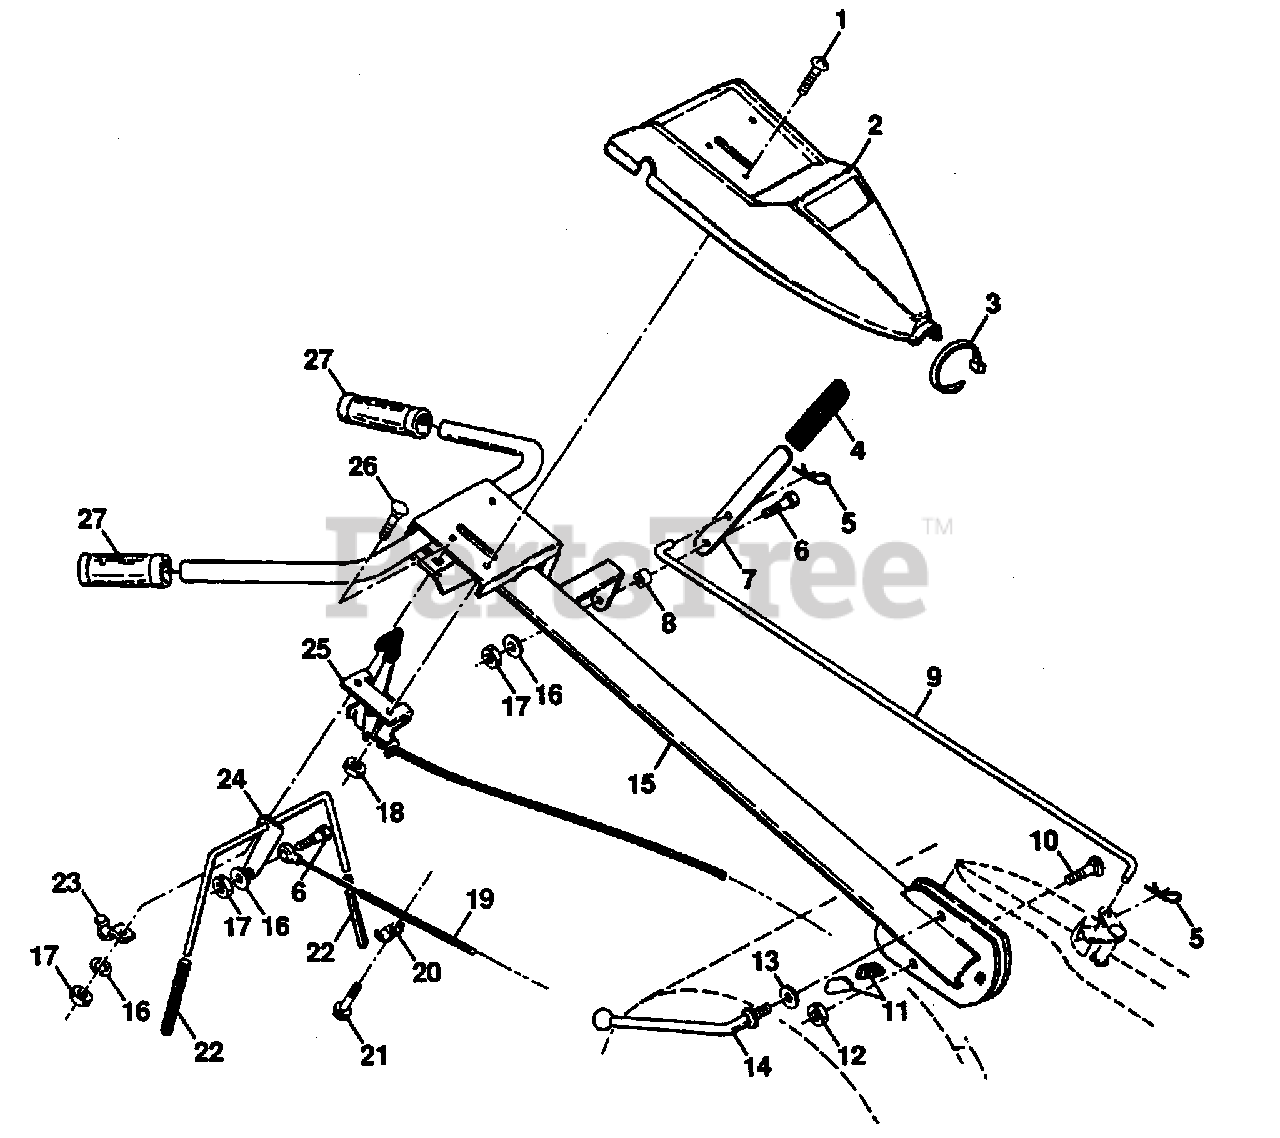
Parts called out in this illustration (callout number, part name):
1	Screw, Truss Hd. #10-24 UNC x 1/2 (AYP part number)
2	Panel, Control (AYP part number)
3	Tie, Cable (AYP part number)
4	Grip, Handle (AYP part number)
5	Clip, Hairpin (AYP part number)
6	Bolt, Shoulder (AYP part number)
7	Handle, Shift (AYP part number)
8	Grommet, Rubber (AYP part number)
9	Rod, Shift (AYP part number)
10	Bolt, Carriage 3/8-16 x 1 Gr. 5 (AYP part number)
11	Lock, Handle (AYP part number)
12	Nut 3/8-16 (AYP part number)
13	Washer 13/32 x 1 x 11 Ga. (AYP part number)
14	Lever, Lock, Handle (AYP part number)
15	Handle (AYP part number)
16	Washer, Lock 1/4 (AYP part number)
17	Nut, Hex 1/4-20 (AYP part number)
18	Nut, Keps #10-24 UNC (AYP part number)
19	Cable, Clutch (AYP part number)
20	Clip (AYP part number)
21	Screw, Hex Washer Hd. Slotted #10-24 x 1/2 (AYP part number)
22	Grip, Bar, Control (AYP part number)
23	Clamp, Bar, Control (AYP part number)
24	Bar Assembly, Control (AYP part number)
25	Control, Throttle (AYP part number)
26	Bolt, Carriage 1/4-20 UNC x 1/2 (AYP part number)
27	Grip, Handle (AYP part number)
